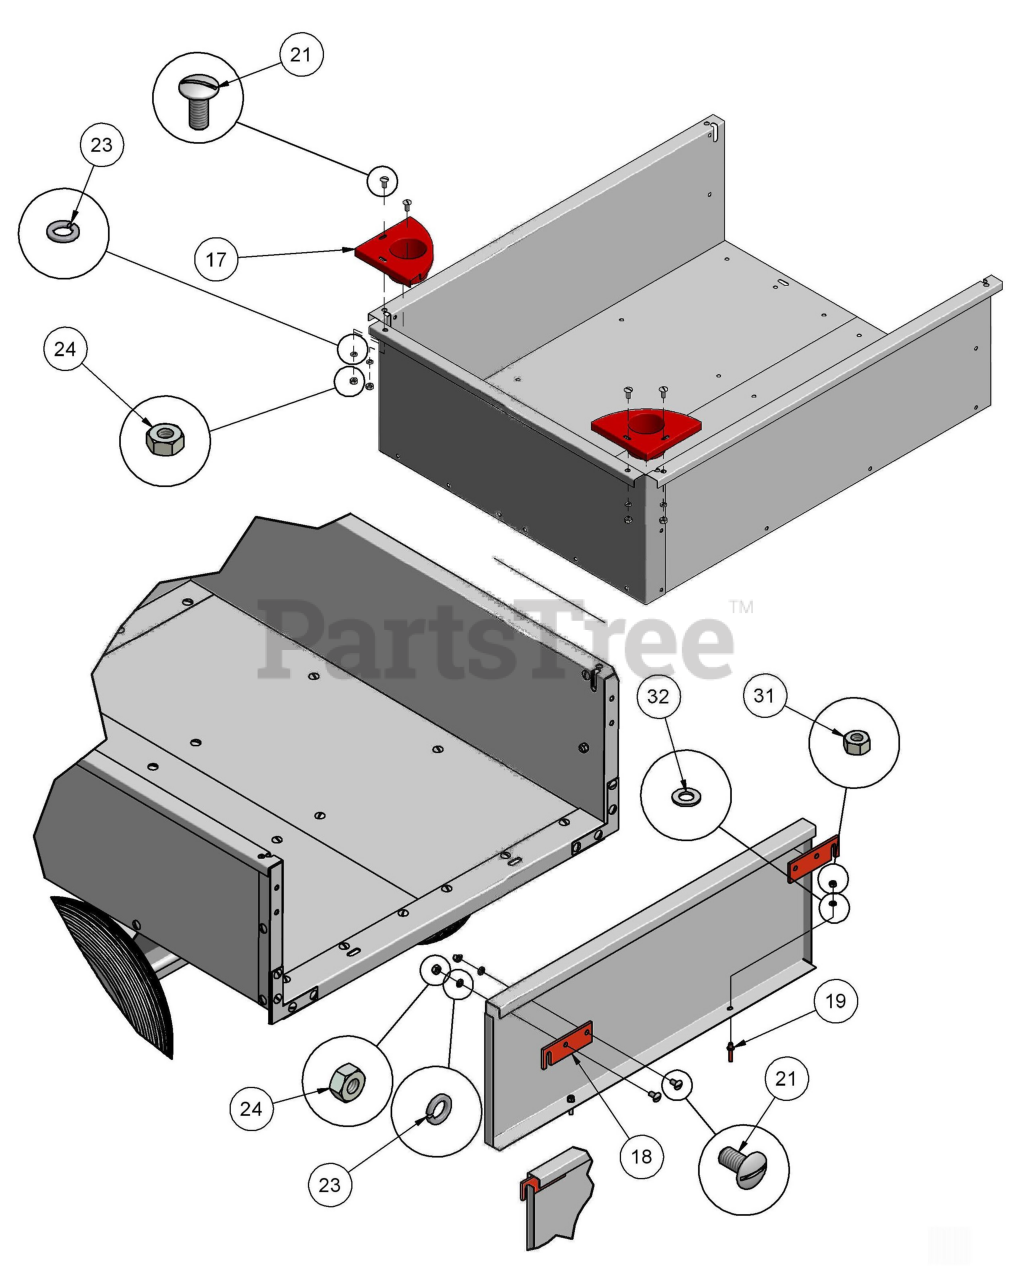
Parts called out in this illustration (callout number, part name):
17	FRONT CORNER BRACE
18	TAILGATE LATCH
19	TAILGATE PIN
21	M8 X 16 TRUSS HEAD BOLT
23	8MM LOCK WASHER
24	8MM HEX NUT
31	6MM HEX NUT
32	6-8MM FLAT WASHER
